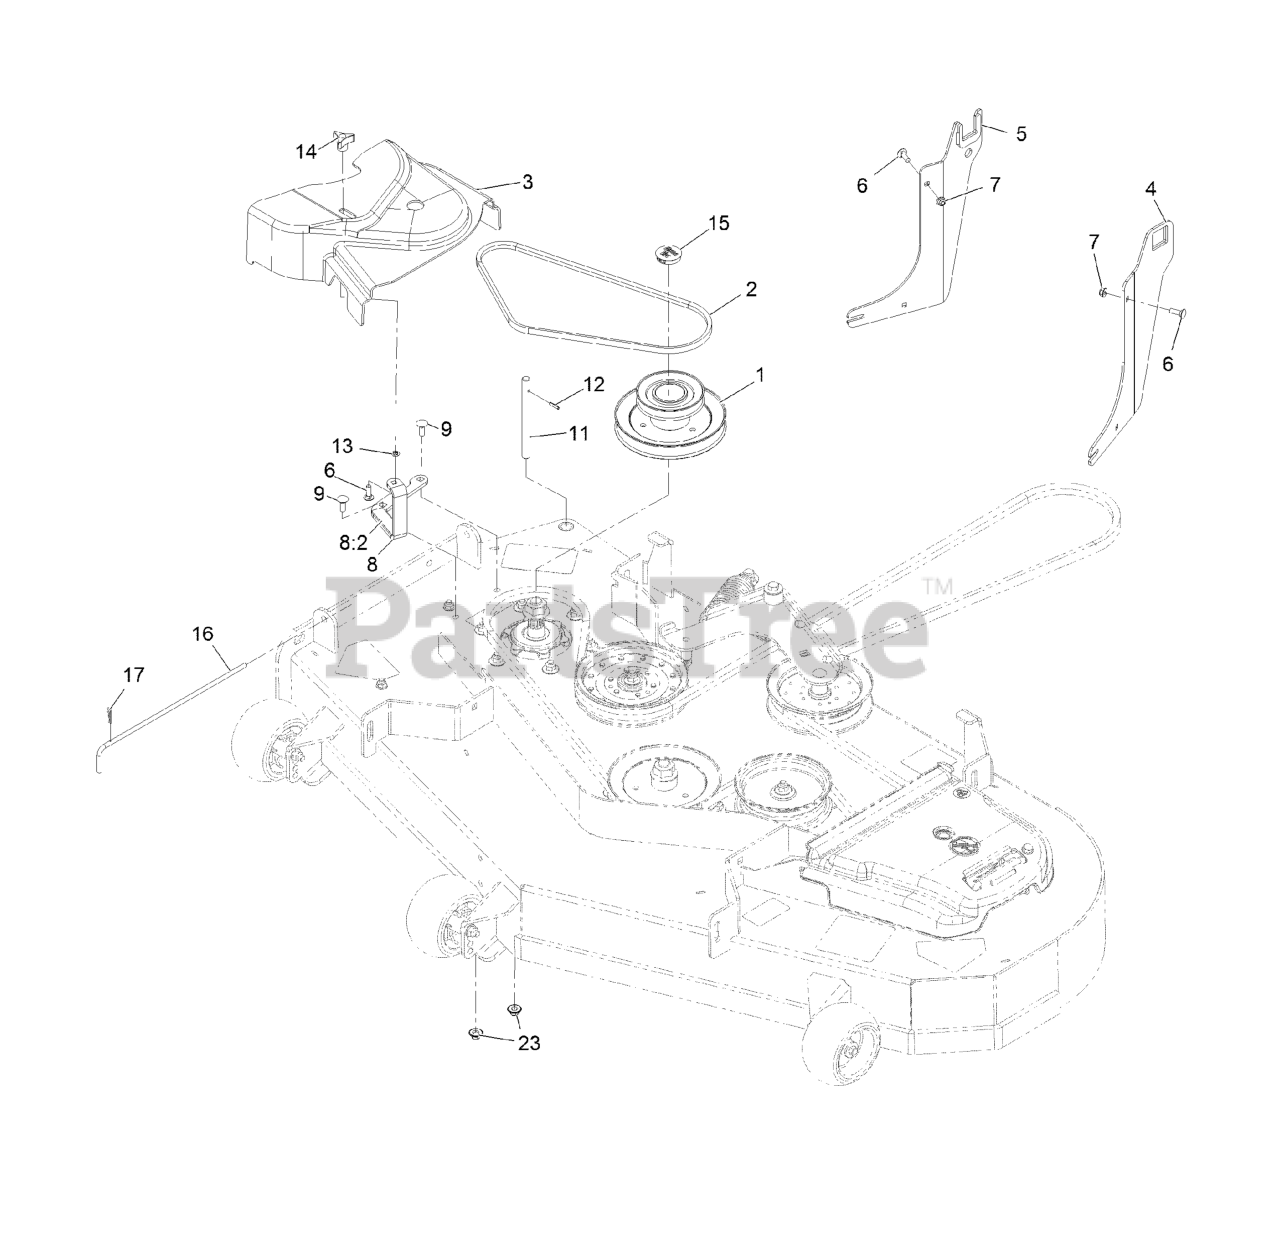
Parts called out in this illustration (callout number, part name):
1	JACKSHAFT-UV DRIVE 52 SPL
2	BELT-BLOWER
3	COVER-BELT, UV 52
4	BRACKET ASM, LH
5	BRACKET ASM, RH
6	BOLT-CARR
7	NUT-HF, NI
8	ASM-CVR BRKT W/DECAL
8:2	DECAL-DANGER
9	BOLT-CARR
11	SHAFT-CATCHER, GRASS
12	PIN-ROLL
13	RING-RETAINING, BOLT
14	KNOB-3 PRONG
15	PLUG, BLACK NYLON 1.75
16	PIN,CHUTE PIVOT
17	PIN-COTTER
23	Nut-Nyloc 3/8-16 Flg
